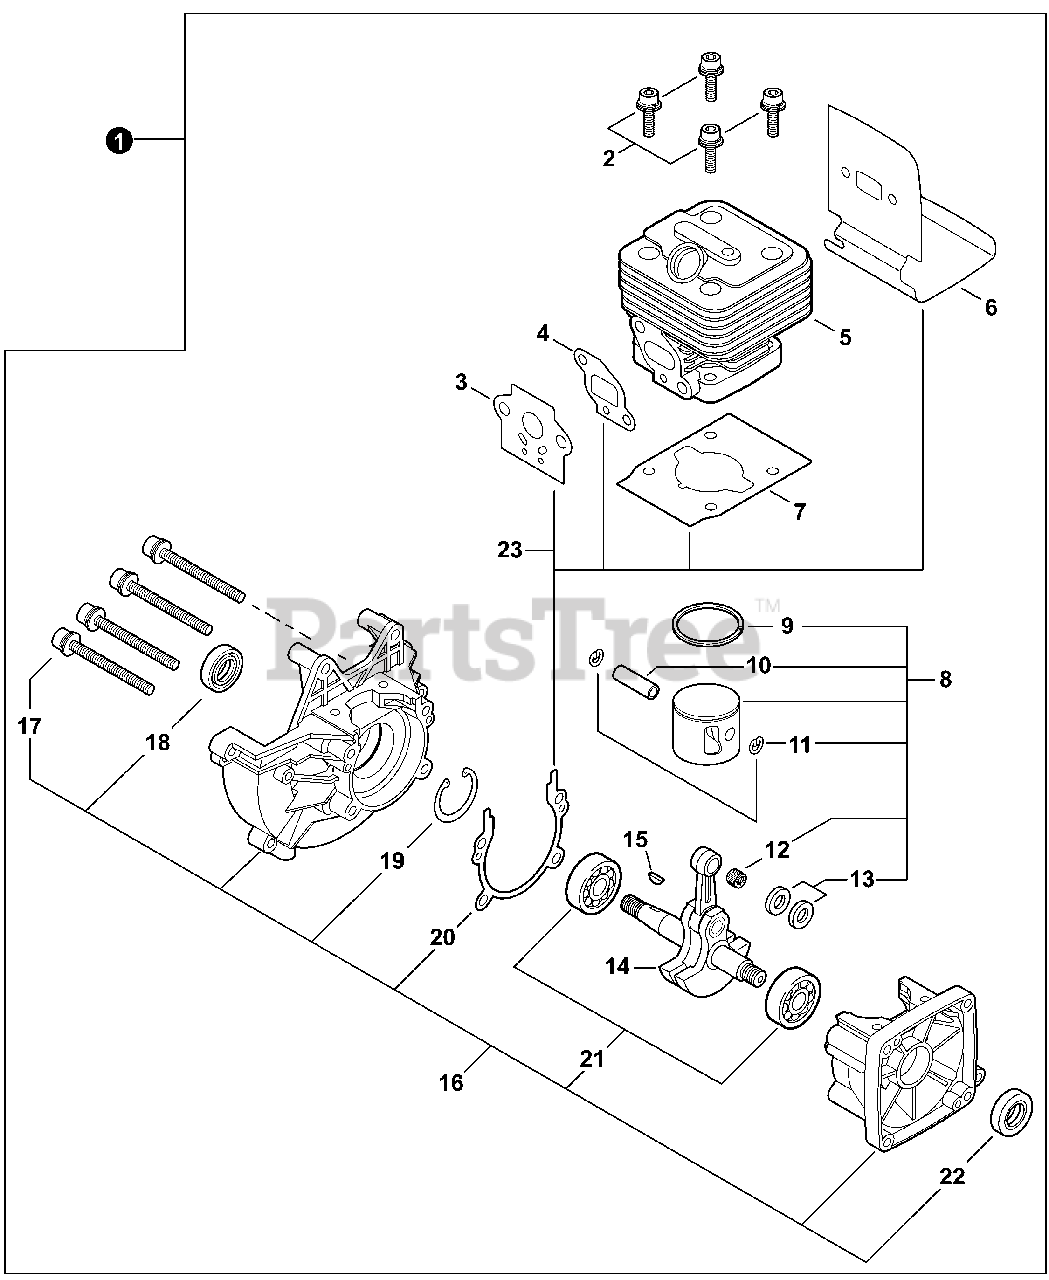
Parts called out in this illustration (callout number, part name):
1	SHORT BLOCK
2	SCREW 5×25
3	GASKET, INTAKE
4	GASKET, INTAKE
5	CYLINDER
6	HEAT SHIELD, EXHAUST
7	GASKET, CYLINDER
8	PISTON KIT
9	RING, PISTON
10	PIN, PISTON
11	RING, SNAP
12	BEARING, NEEDLE 9
13	WASHER, THRUST
14	CRANKSHAFT ASSY
15	KEY, WOODRUFF
16	CRANKCASE KIT
17	BOLT 5×28
18	SEAL, OIL 12
19	RING, SNAP Ø32
20	GASKET, CRANKCASE
21	BEARING, BALL - 6201 C3
22	SEAL, OIL 12
23	GASKET KIT
